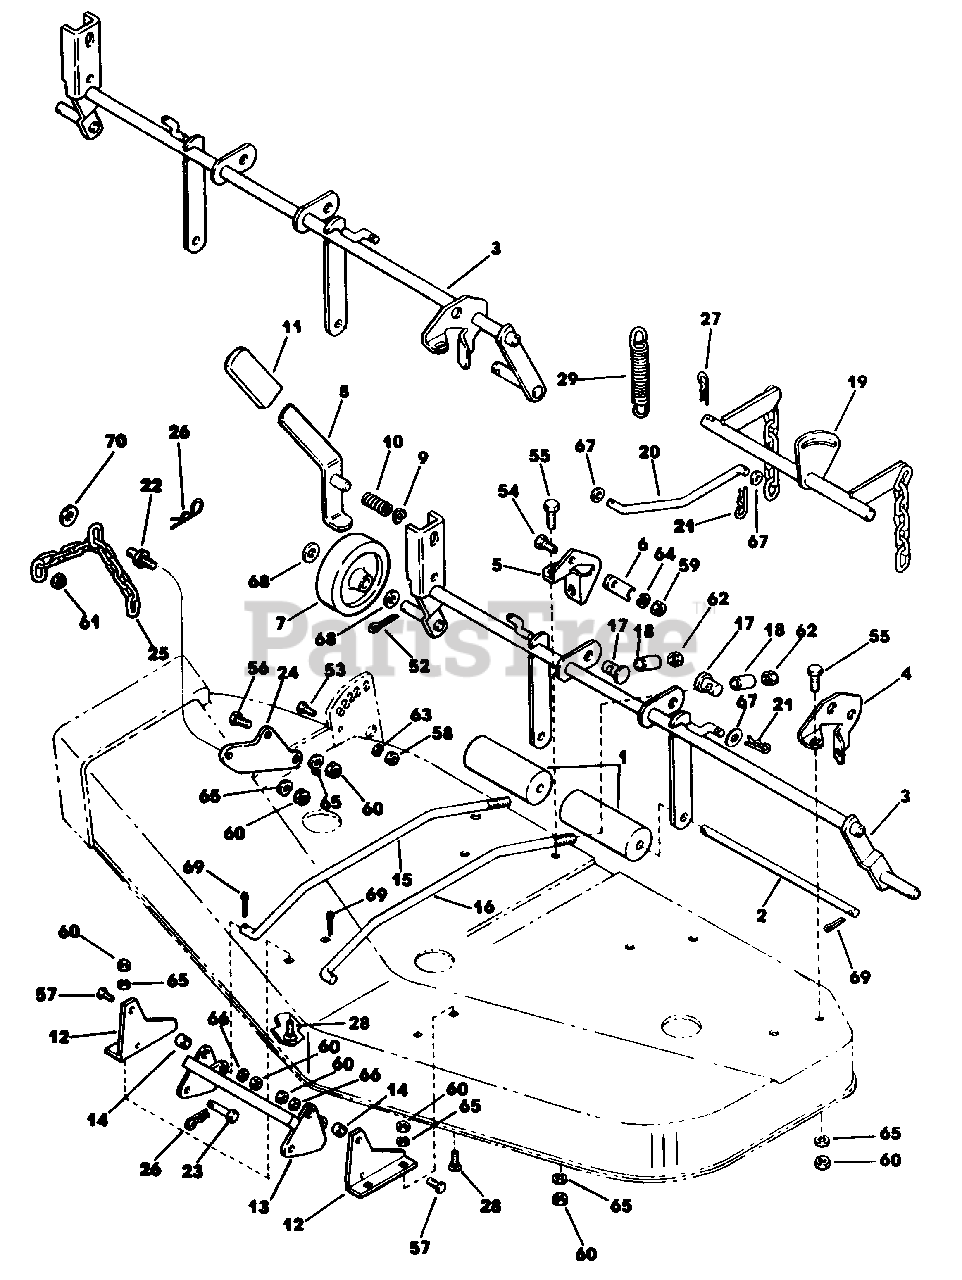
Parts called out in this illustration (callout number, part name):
1	Roller
2	Shaft, Roller
3	Hanger Assembly, Wheel (42" Only)
4	Support, Wheel L.H. (42" Only)
5	Support, Wheel Center
6	Strap-Middle Support
7	Wheel-Mower
8	Handle Assembly-Height Adjustment
9	Washer, Wave
10	Spring
11	Grip
12	Bracket, Front Hanger Mounting
13	Front Hanger Assembly
14	Bushing, Pivot
15	Rod, Level R.H. (42" Only)
16	Rod, Level R.H. (48" Only)
17	Pin, Pivot
18	Spacer
19	Bellcrank Assembly
20	Link, Mower Lift
21	Spring Clip
22	Lift Clevis Pin
23	Clevis Pin
24	Arm, Front Lift
25	Chain
26	Spring Clip
27	Spring Clip
28	Bolt Carriage 3/8-16 x 3/4
29	Spring
52	Pin, Cotter 3/16 x 1" Plated
53	Cap Screw, Hex Hd. 1/4-20 x 1-1/2 Plated, Grade 5
54	Cap Screw Hex Hd. 5/16-18 x 3/4 Plated, Grade 5
55	Cap Screw Hex Hd. 3/8-16 x 7/8 Plated, Grade 5
56	Cap Screw Hex Hd. 3/8-16 x 1" Plated, Grade 5
57	Cap Screw Hex Hd. 3/8-16 x 1-3/4 Plated, Grade 5
58	Nut, Hex 1/4-20 Plated
59	Nut, Hex 5/16-18 Plated
60	Nut, Hex 3/8-16 Plated
61	Nut, Hex Cone Lock 3/8-16 Plated
62	Nut, Hex Cone Lock 1/2-13 Plated
63	Washer, Spring Lock 1/4 Plated
64	Washer, Spring Lock 5/16 Plated
65	Washer, Spring Lock 3/8 Plated
66	Washer, Flat 3/8 Plated
67	Washer, Flat SAE 3/8 Plated
68	Washer, Flat SAE 5/8 Plated
69	Cotter Pin 1/8 x 3/4 Plated
70	Washer, Flat SAE 5/16 Plated
